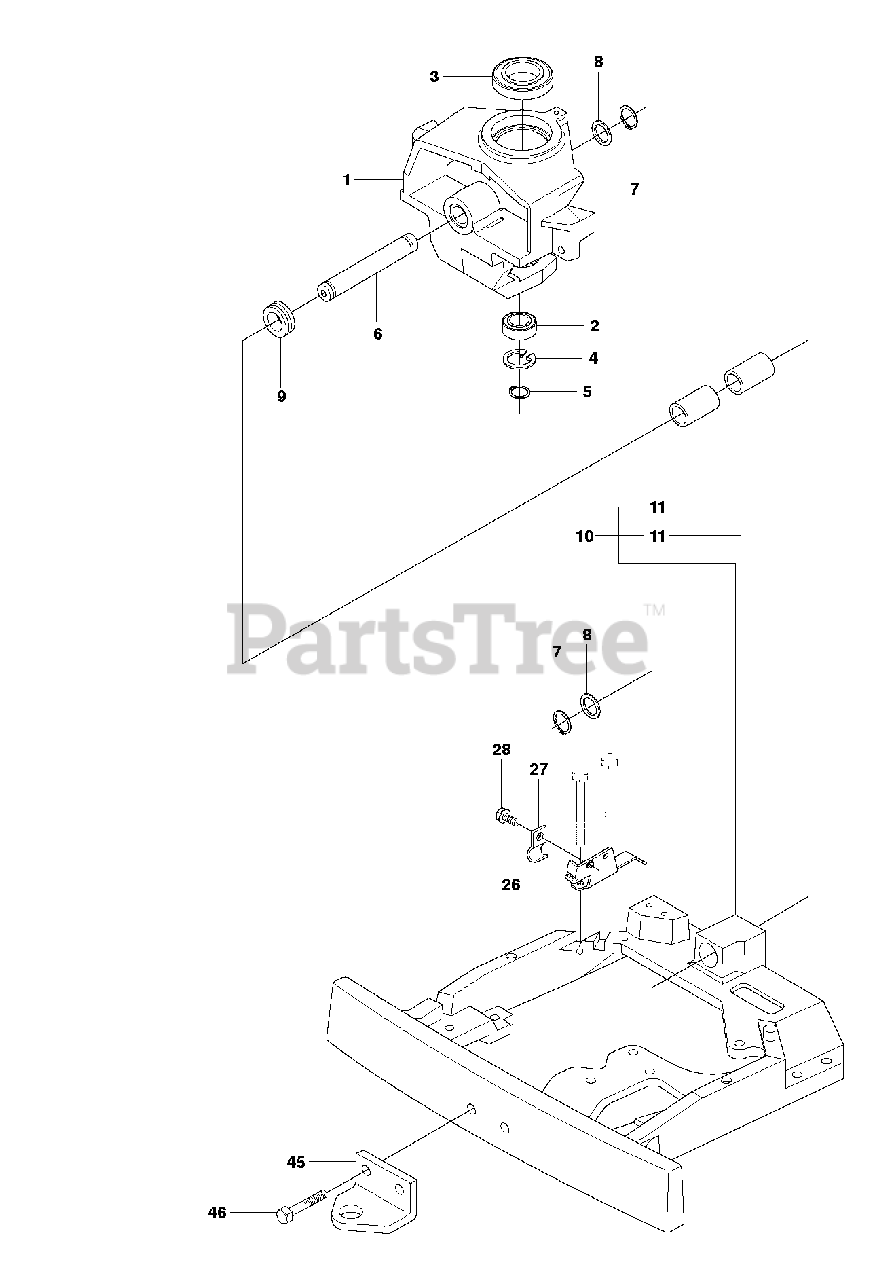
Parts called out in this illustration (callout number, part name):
2	BALL BEARING 6005-2RS
3	BALL BEARING 6010 2RS1
4	CIRCLIP SGH 47
5	RETAINING RING SGA 25
7	RETAINING RING SGA 25
11	BUSHING
45	DRAW RING
46	SCREW M10X25
